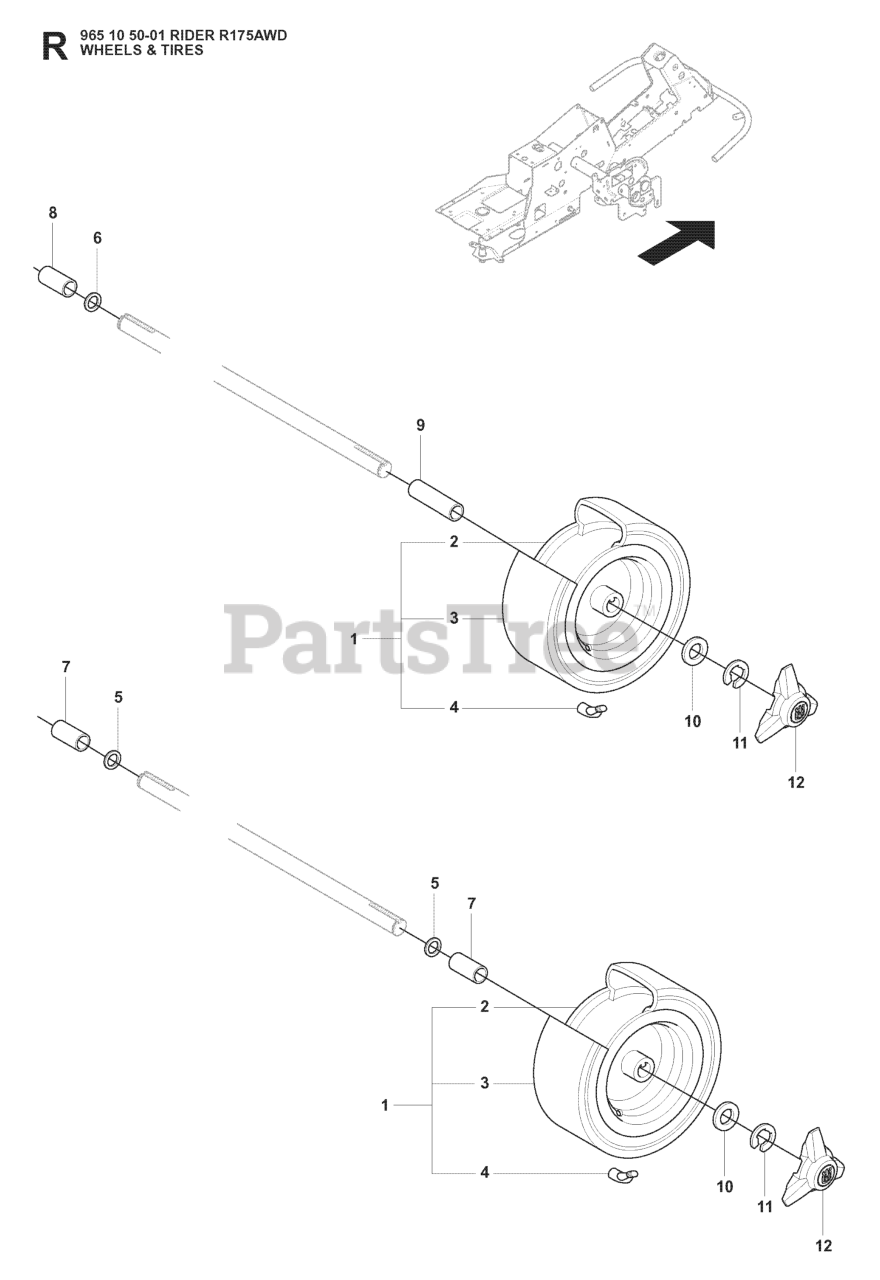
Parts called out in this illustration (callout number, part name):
1	WHEEL
2	RP RIM
7	SPACE SLEEVE
11	RETAINING RING
